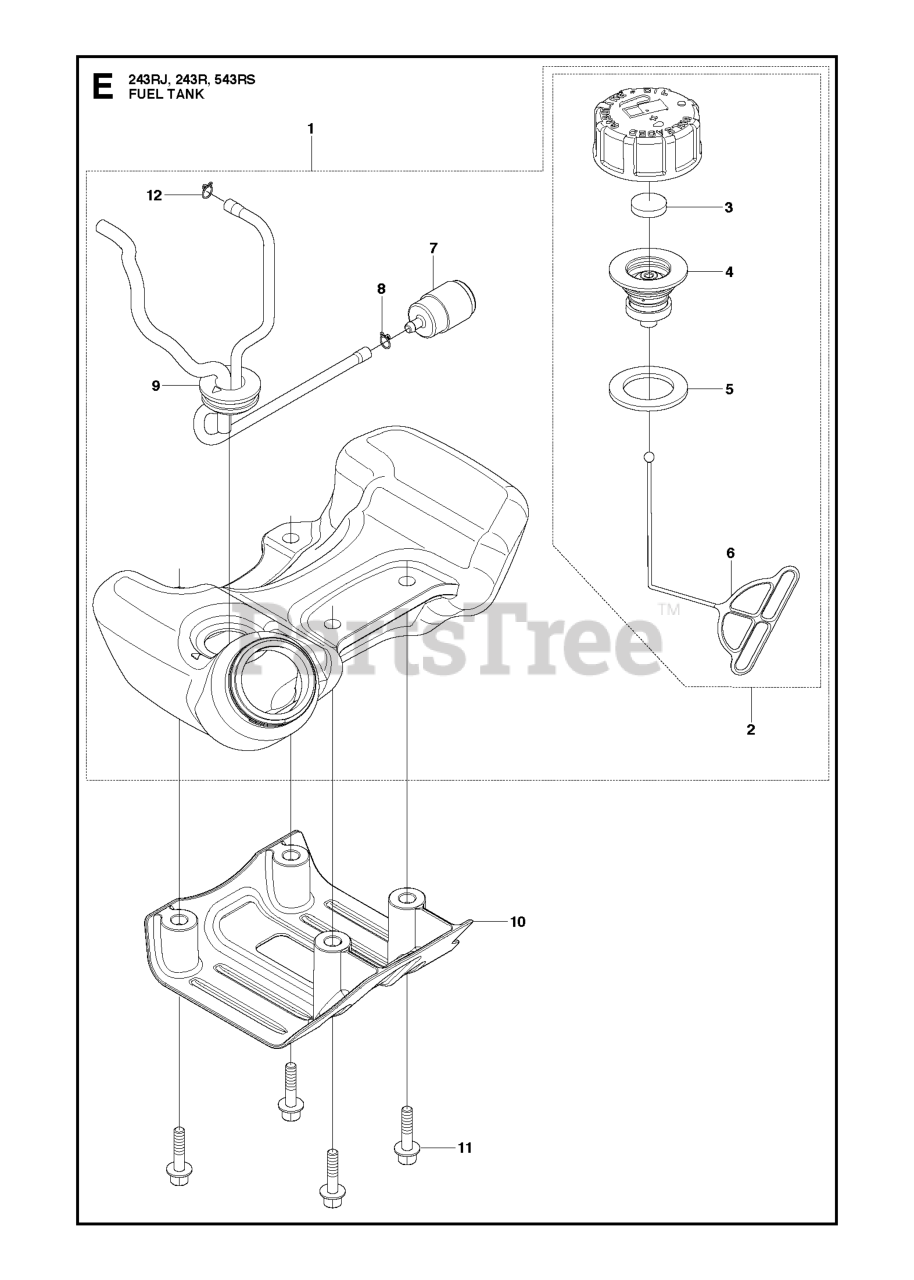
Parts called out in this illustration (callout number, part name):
1	TANK-ASSY 848GG08501
1	TANK ASSY
2	ASSY FUEL CAP
3	FILTER
4	HOLDER-A
5	PACKING
6	STOPPER
7	FILTER ASSY
8	CLIP
9	PIPE-COMP 848GG08530
9	PIPE COMP
10	GUARD, TANK
11	BOLT M5X25
12	CLAMP FUEL LINE
